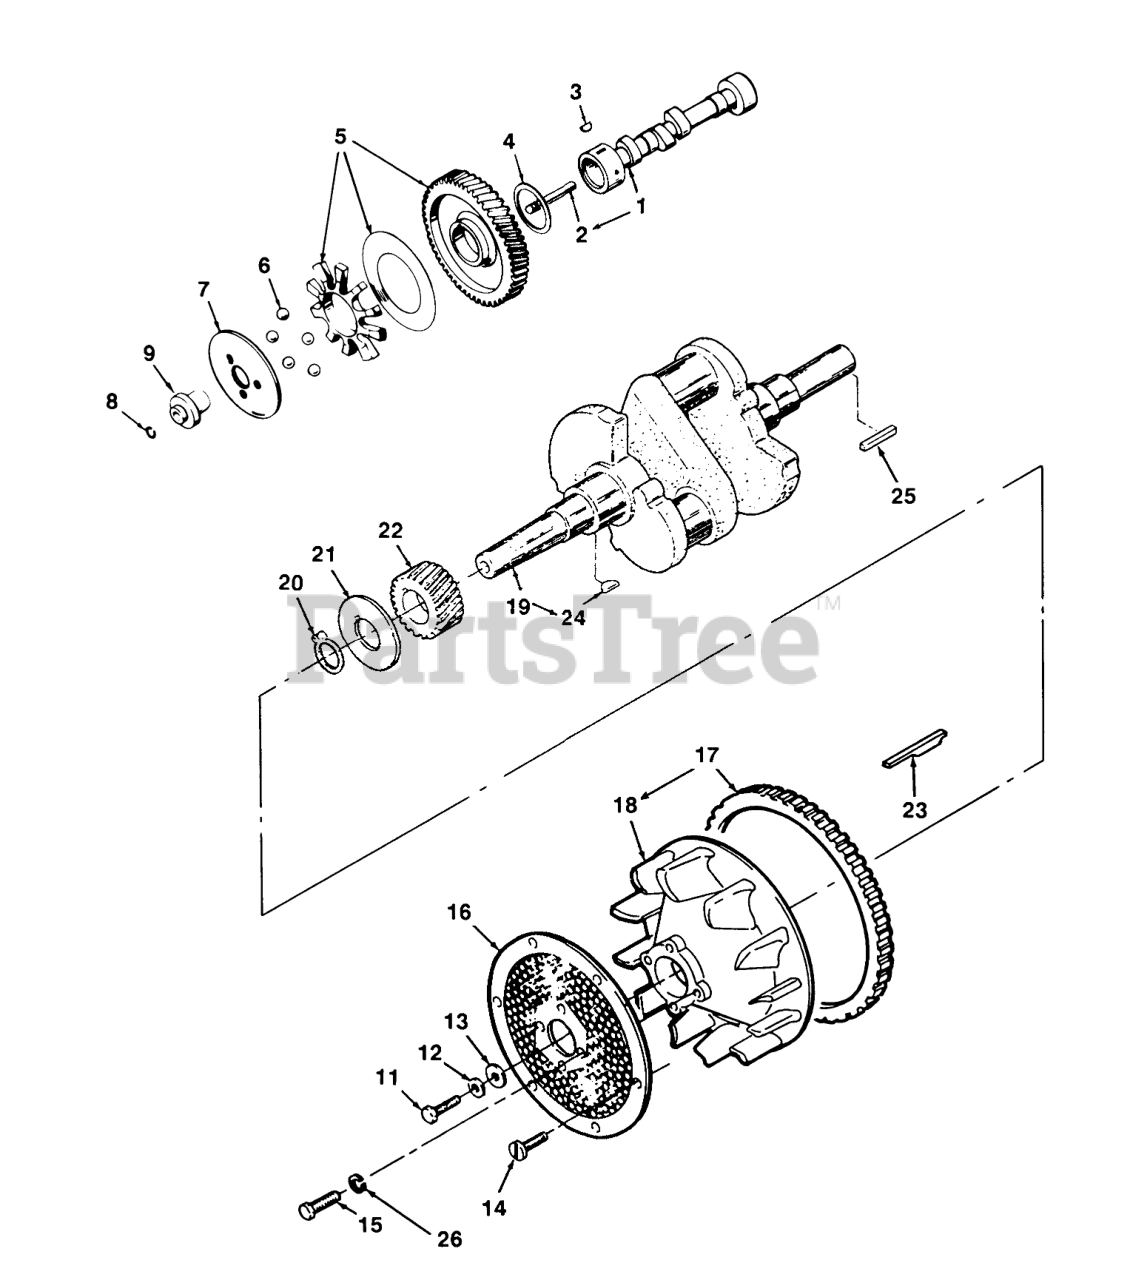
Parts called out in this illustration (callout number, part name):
1	Camshaft (Incl. Center Pin)
2	PIN-CENTER
4	WASHER-THRUST
5	Gear-Camshaft (Incl. Plate & Spacer)
6	BEARING
7	CUP-GOVERNOR
9	HUB-GOVERNOR CUP
11	Bolt-Special
12	WASHER-FLAT
13	WASHER-FLAT
14	Bolt
15	HX HD LOCK CAPSCREW
16	Screen
17	Gear-Ring
18	Flywheel (Incl. Ring-Gear)
19	Crankshaft (Incl. Keys)
21	WASHER
22	GEAR-CRANKSHAFT
23	KEY-FLYWHEEL
25	Key
26	WASHER - LOCK (5/16")
